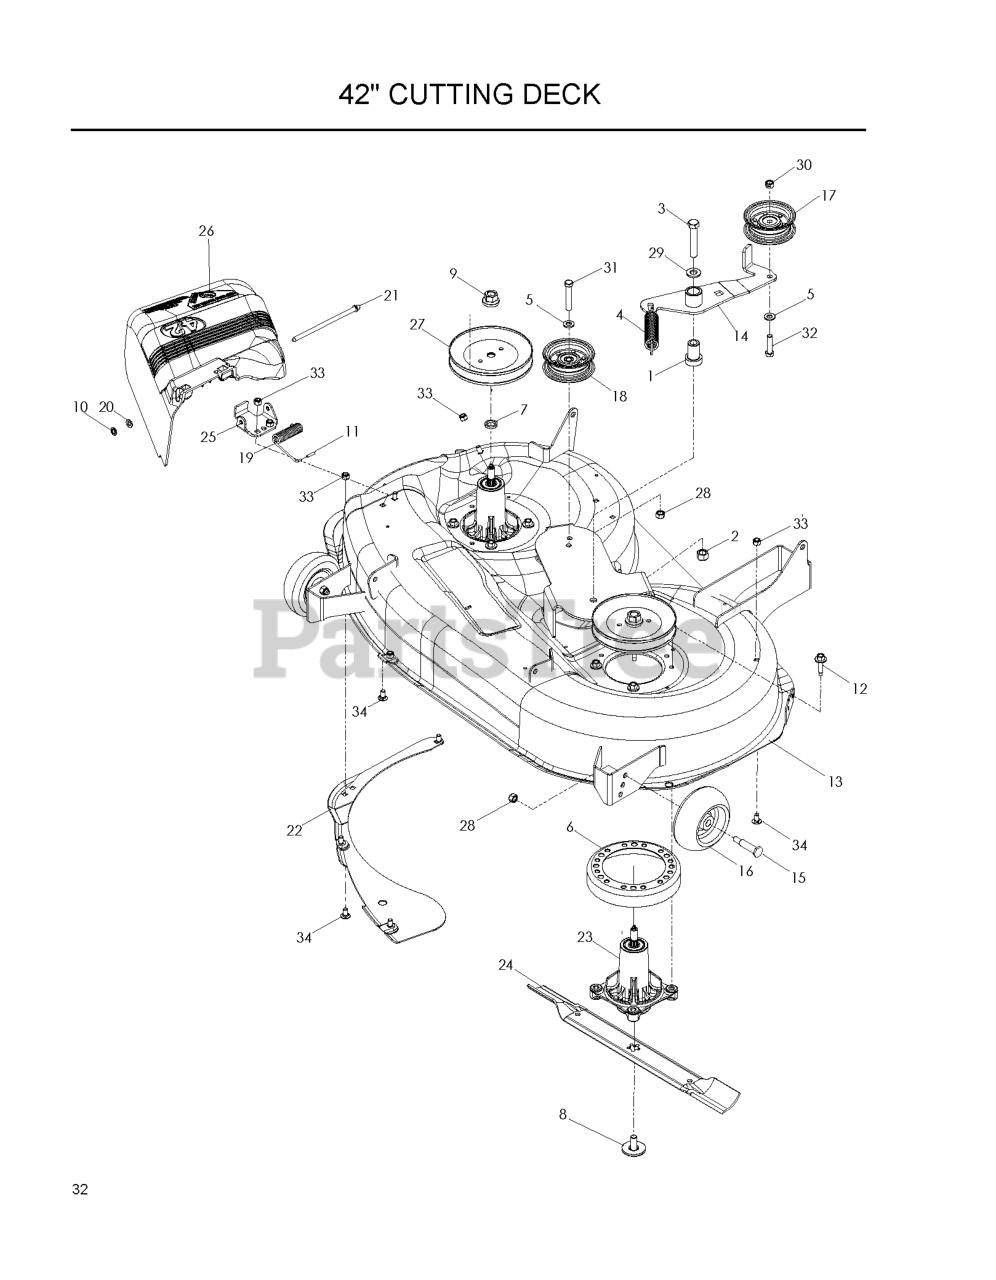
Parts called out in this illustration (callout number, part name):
1	IDLER SPINDLE
2	NUT 1/2-13 HEX NYLOC ZD
3	HCS 1/2C X 2 3/4
5	WASHER 3/8 SAE FLAT
6	STRIPPER-ROUND-UNIVERSAL
7	WASHER-SPACER
8	BOLT.WASHER.ASM.7/16-2
9	LOCKNUT - 9/16
10	PUSH NUT
11	CAP-SLEEVE
12	WASHER HEAD SCREW
13	DECK W/DECALS 42" ORANGE
14	DECK IDLER ARM WELDMENT
15	BOLT, SHOULDER
16	WHEEL GUAGE
17	PULLEY, IDLER, SHORT
18	IDLER PULLEY ASM
19	SPRING, TORSION DEFLECTOR
20	WASHER, 11/32 X 5/8 X 16 GA
21	ROD, HINGE
22	BAFFLE VORTEX 42
23	MANDREL GREASABLE
24	BLADE 42" MULCHING STD
25	BRKT.DEFLECTOR.38"2005+
26	DEFLECTOR 42
27	PULLEY.MANDREL.5.438.P
28	NUT 3/8-16 NYLOC
29	WASHER 1/2" FLAT
30	NUT 3/8C CENTERBLOCK
31	HCS 3/8C X 2 1/4
32	HCS 3/8C X 1 1/2
33	NUT 5/16 NYLOC
34	CARRIAGE BOLT 5/16C X 5/8"
35	BELT, V MOWER DECK 42"
